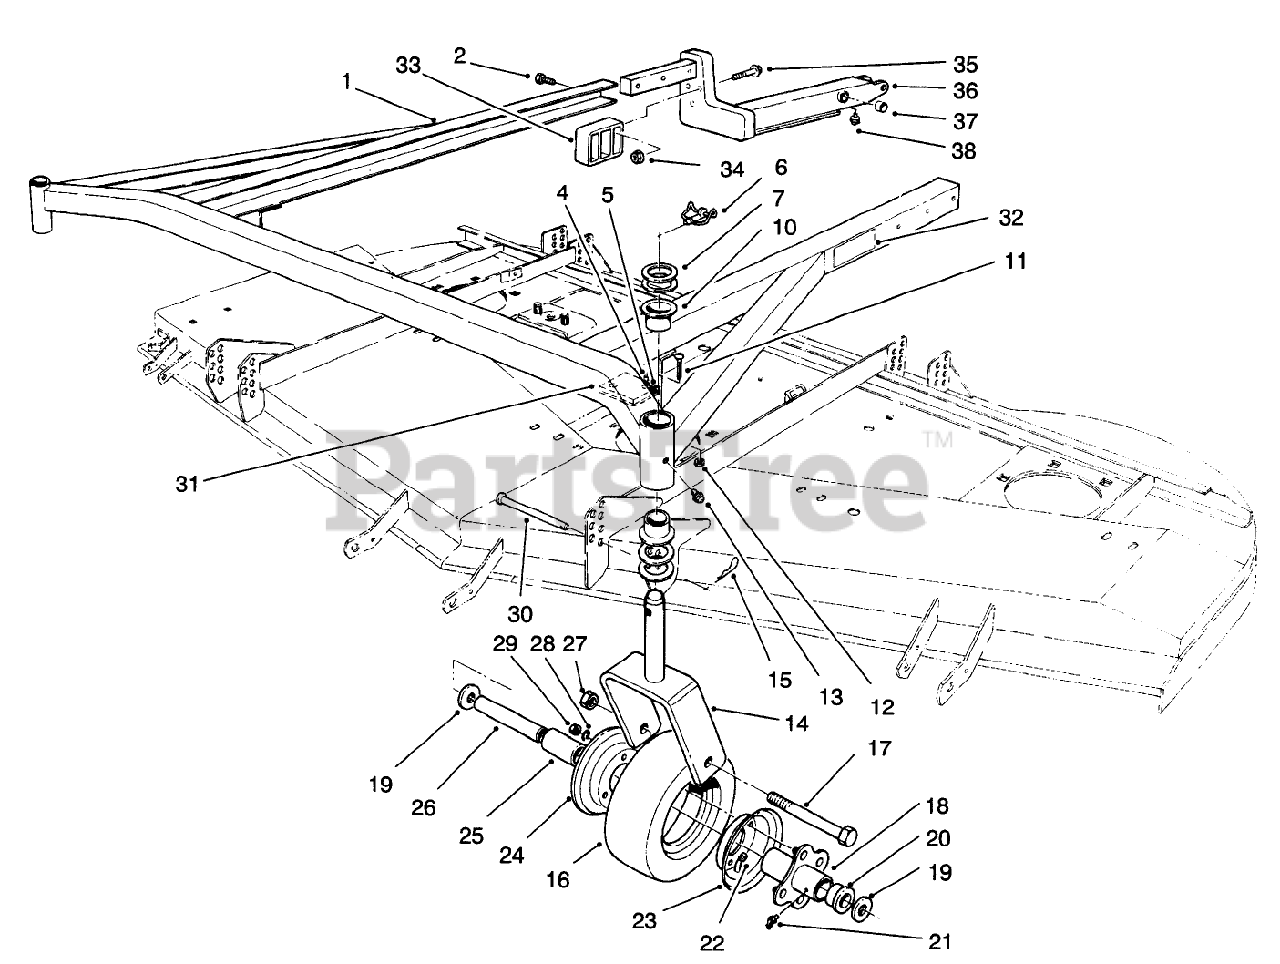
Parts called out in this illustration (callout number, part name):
1	Carrier Frame Assembly (Incl. Ref. #10 & 13)
2	SCREW-HH
4	SPACER
5	CUSHION-RUBBER
6	PIN-LYNCH
7	WASHER-THRUST
10	BUSHING
12	NUT-LOCK, NI
13	FITTING-GREASE
14	Castor Fork
15	PIN-HAIR
17	SCREW-HH
18	HUB-CENTER
19	WASHER-FLAT
20	BEARING-OUTSIDE
21	FITTING-GREASE
22	TUBE-INNER (W/VALVE)
23	FEMALE WHEEL HALF
24	MALE WHEEL HALF
25	BEARING-ROLLER
26	SPANNER-TIRE
27	NUT-HEX
28	WASHER-LOCK
29	NUT-HEX
30	PIN-CLEVIS
31	SHIM-CUSHION
32	DECAL-HOC, LH
33	Cradle-Rear
34	NUT-FLANGE
35	SCREW-HHF
36	Lift Arm R.H. (Incl. Ref. # 37 & 38)
37	BUSHING
38	FITTING-GREASE
